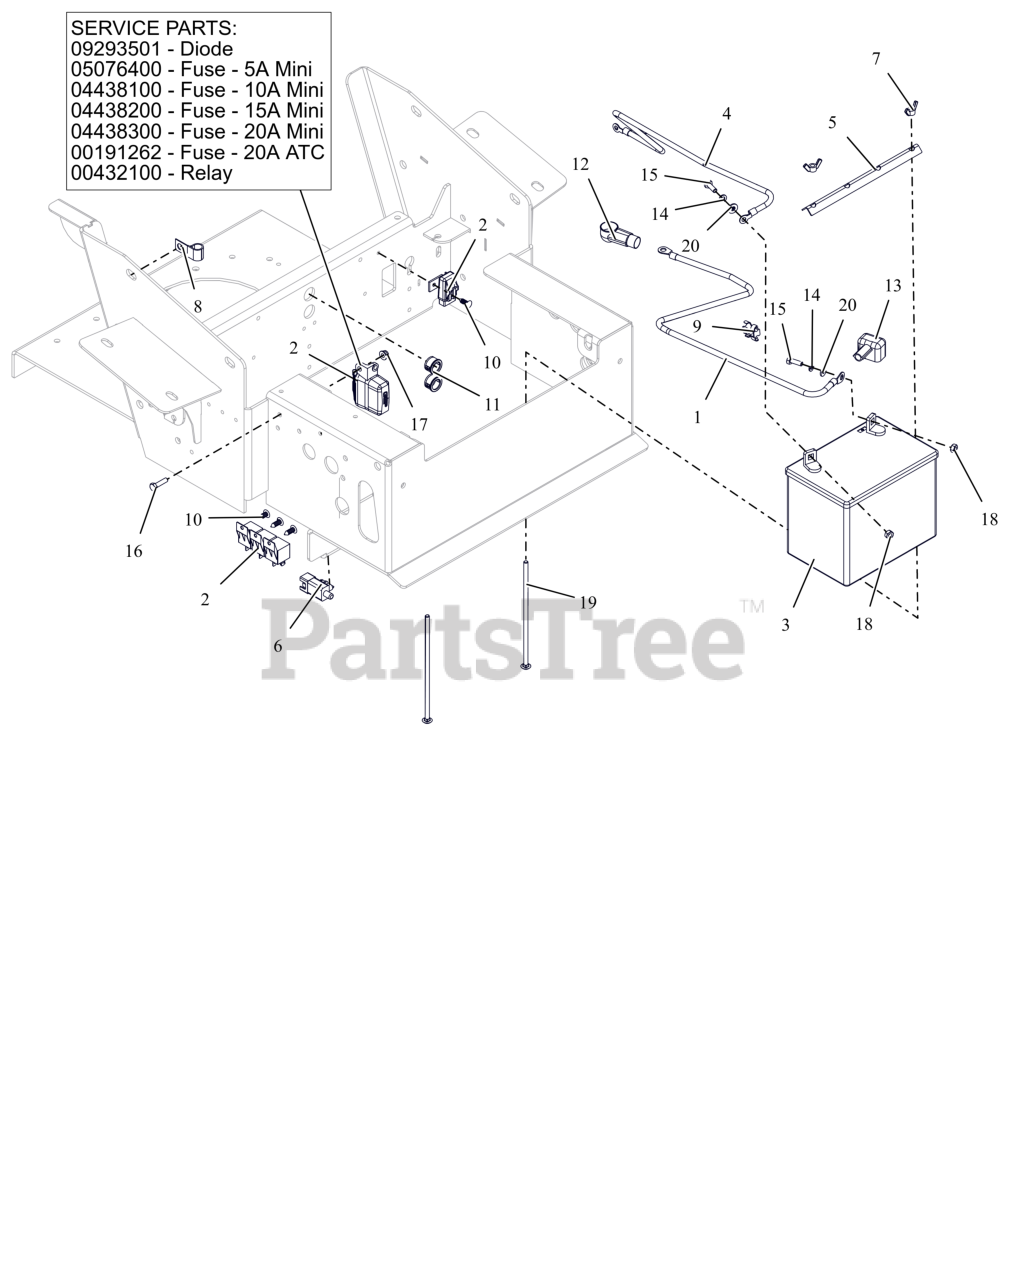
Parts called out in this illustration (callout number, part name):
1	CABLE,POS W/(2) 5/16 RING 30LG
2	HARNESS, PT100 WIRE
3	BATTERY, 300 CCA 10U1L
4	CABLE-NEGATIVE BATTERY 24.00"
5	HOLD DOWN
6	SWITCH, SNAP IN - N.O./N.O.
7	NUT, LK-WING .25-20 ZCC
9	CLIP,T,.31-.38,
10	RIVET, .25 NYLON PANEL
11	BUSH, PANEL SNAP .687X.875X.56
12	BOOT, .65ID POS
13	INSULATOR
14	WSHR,LK-REG .250X.062 ZCC
15	BLT, HEX .25-20X.75 G5 ZCC
16	BLT,HEX .25-20X1.00 G5 ZCC
17	NUT,NYL-FLG .25-20 GF ZCC
18	NUT-STD .250-20 G2 ZCC
19	BTL,RHSN .250-20 X 7.5 G5 ZCC
20	WSHR,FLT .281X.625X.065 ZCC
